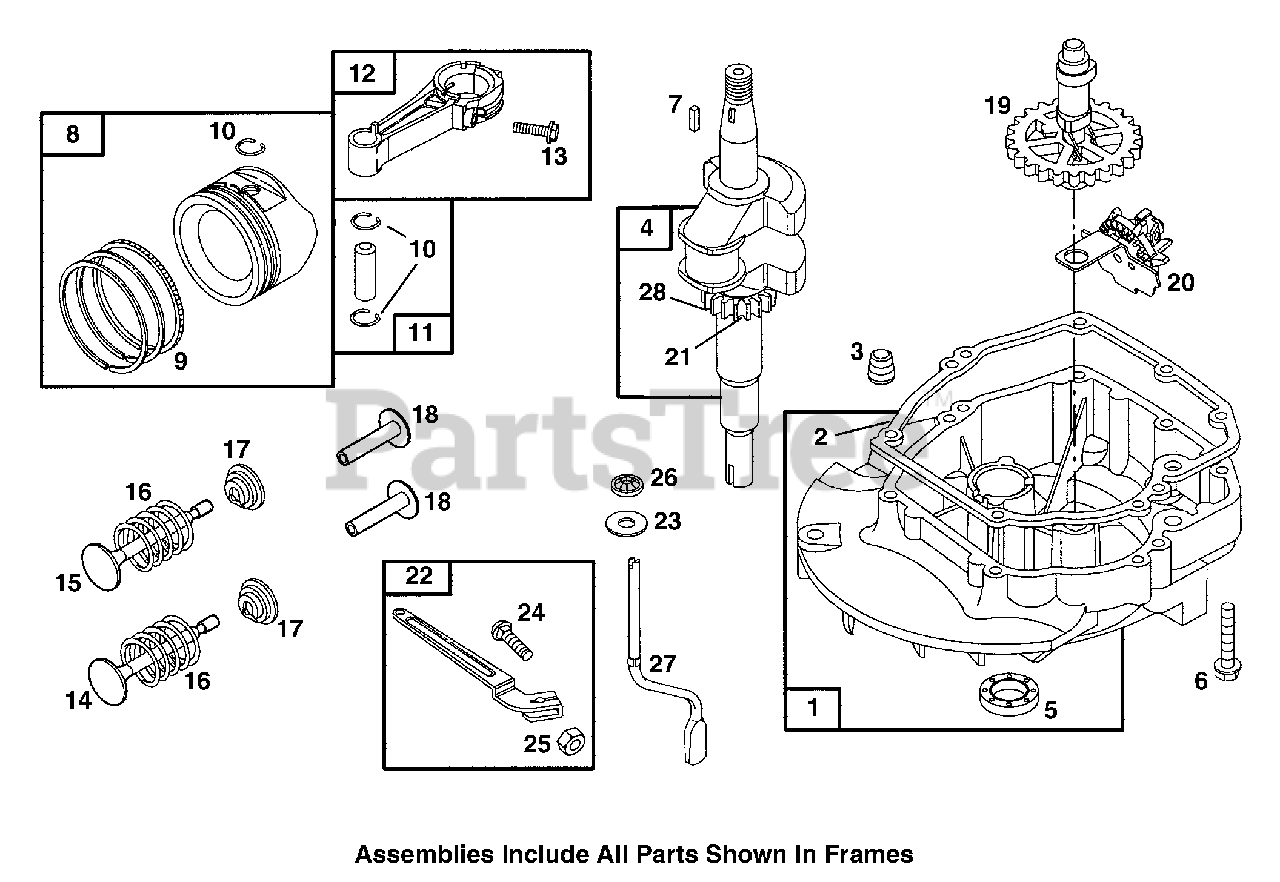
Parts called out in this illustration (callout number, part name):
1	Engine Sump
2	Crankcase Gasket
3	Oil Drain Plug
4	Crankshaft
5	Oil Seal
6	Hex Screw
7	Flywheel Key
8	Piston Assembly (Standard)
9	Ring Set (Standard)
10	Piston Pin Lock
11	Piston Pin (Standard)
12	Connecting Rod
13	Connecting Rod Screw
14	Exhaust Valve
15	Intake Valve
16	Valve Spring
17	Valve Retainer
18	Valve Tappet
19	Cam Gear
20	Governor/Oil Slinger
21	Timing Key
22	Governor Lever
23	Flat Washer
24	Governor Lever Bolt
26	Governor Shaft Retainer
27	Governor Crank
28	Timing Gear
